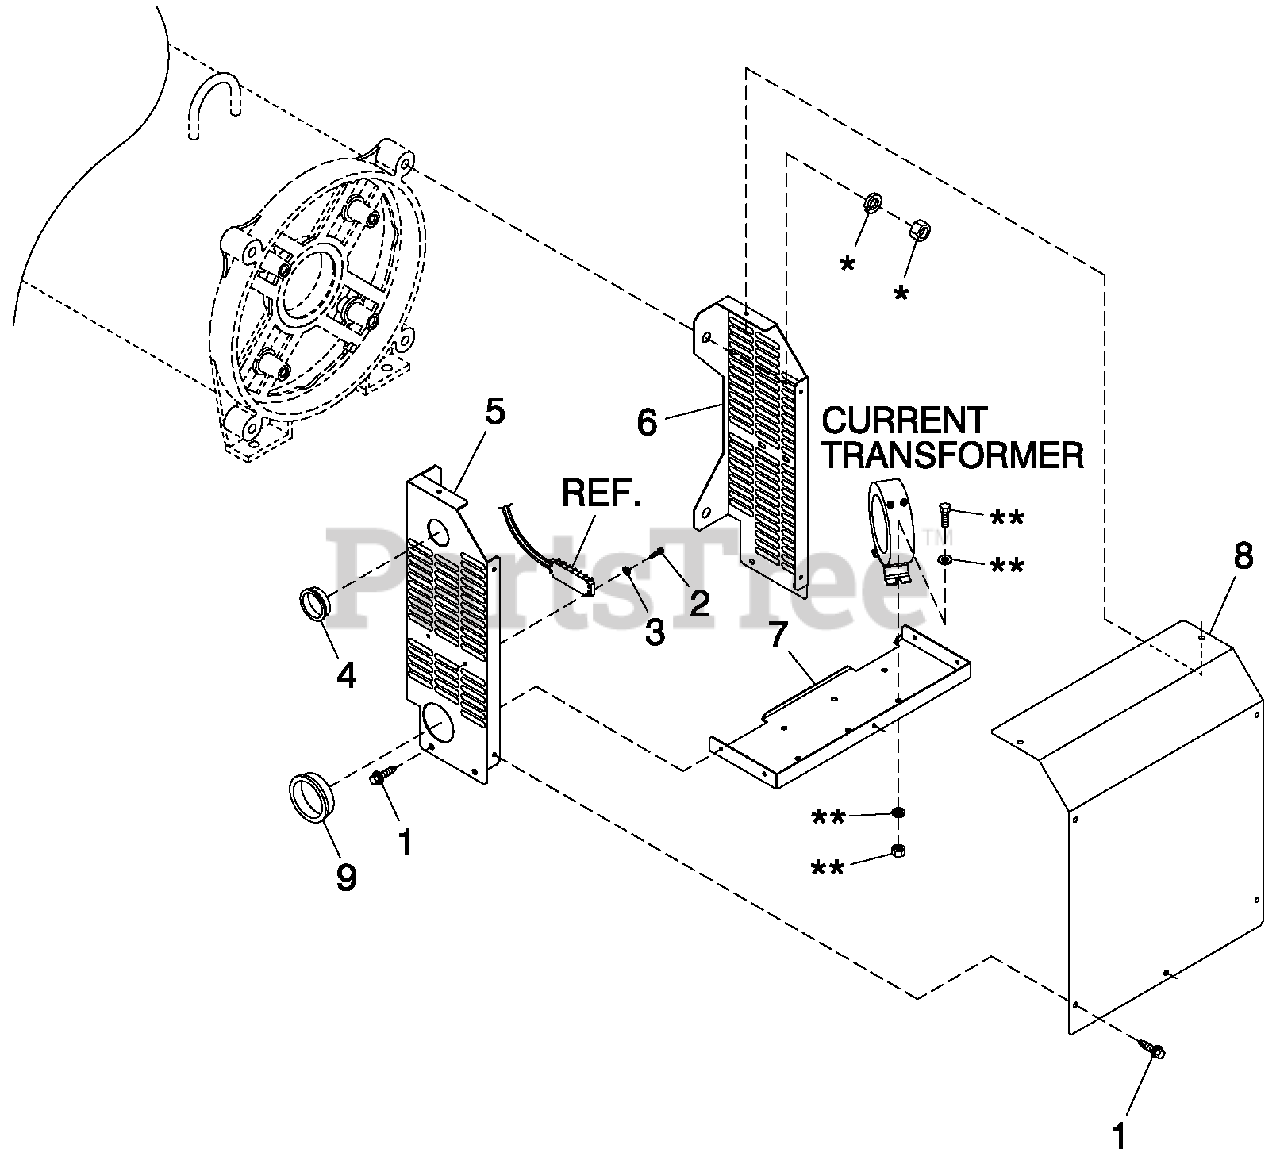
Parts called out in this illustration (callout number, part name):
1	SCREW THF M6-1 X 16 N WA Z/JS
2	SCREW PHTT #6-32 X 1/2 ZYC
3	WASHER LOCK #6
4	BUSHING SNAP SB-1750-22
5	SIDE LH EXCITER SHIELD
6	SIDE RH EXCITER SHIELD
7	B OTTOM EXCITER SHIELD
8	REAR COVER EXCITER SHLD
9	BUSHING SNAP SB-2.5-31
